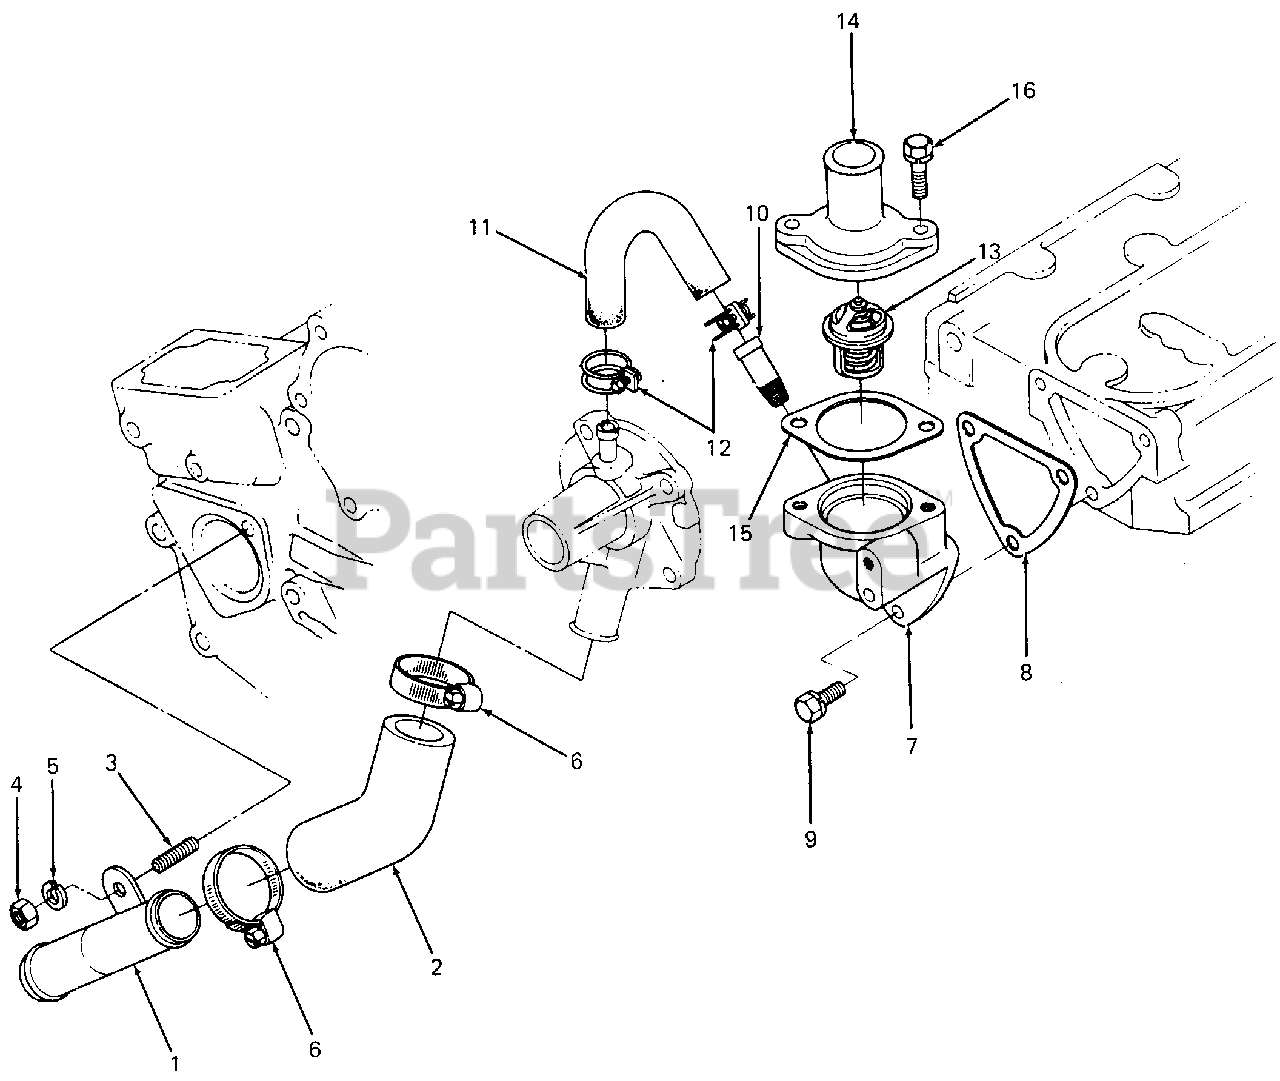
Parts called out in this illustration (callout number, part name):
1	Pipe, Water - 2
2	Pipe, Water - 3
5	Washer, Spring
7	Flange, Water
8	Gasket, Water Flange
9	Screw w/Washer
10	Pipe, Water Return - 1
11	Pipe, Water Return - 2
13	Thermostat
14	Cover, Thermostat
15	Gasket, Thermostat Cover
16	Screw w/Washer
